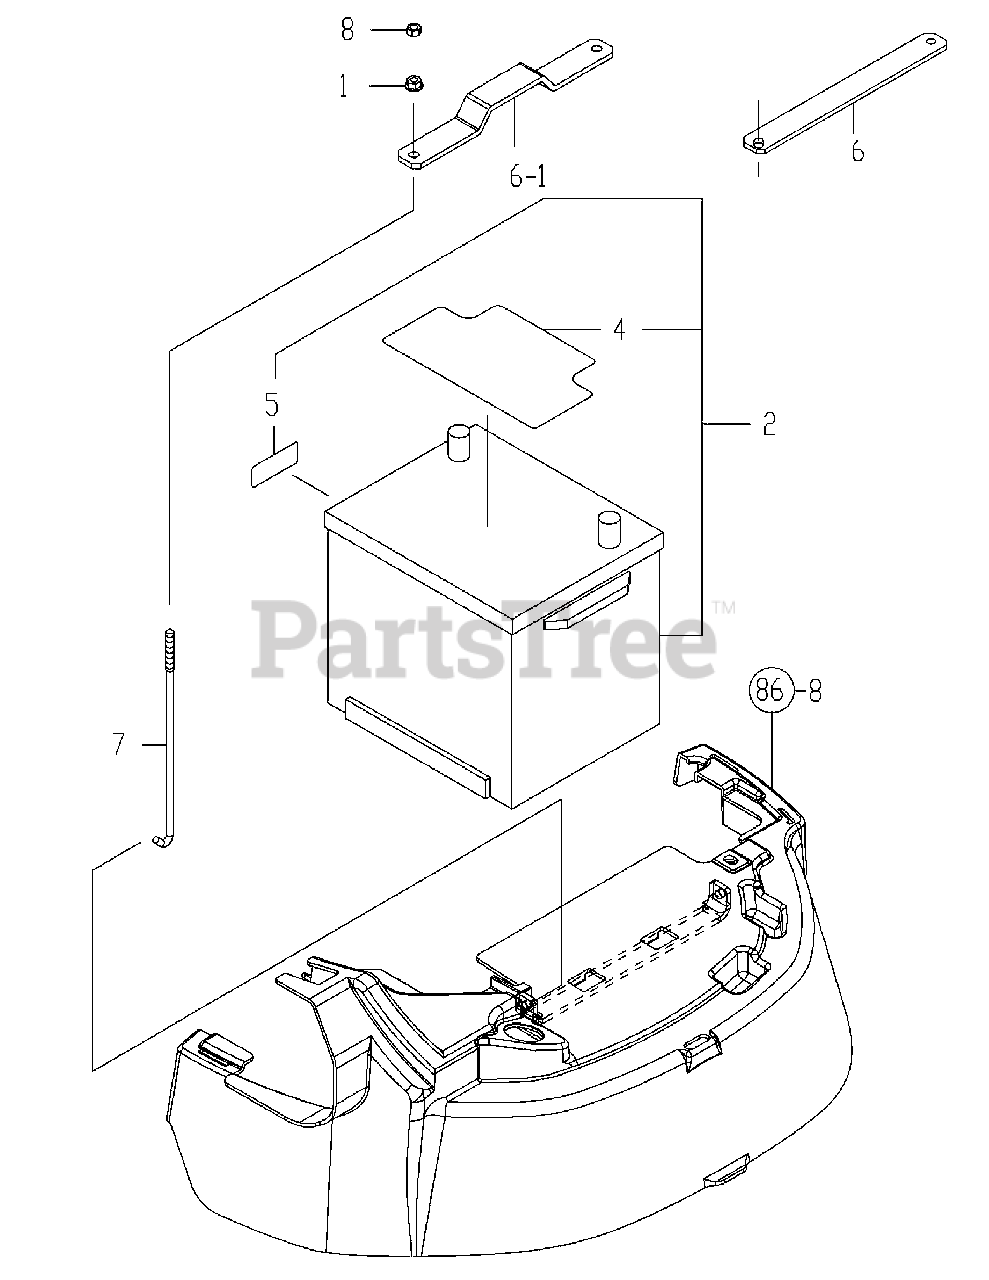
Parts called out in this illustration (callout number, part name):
2	BATTERY, 26R, ASSY 540 CCA Dry
2	BATTERY, 26R, ASSY
4	LABEL, BATTERY
5	LABEL, CA, 65, WARN
6	CLAMP, BATTERY
6-1	CLAMP, BATTERY
7	ROD, BATTERY CLAMP
